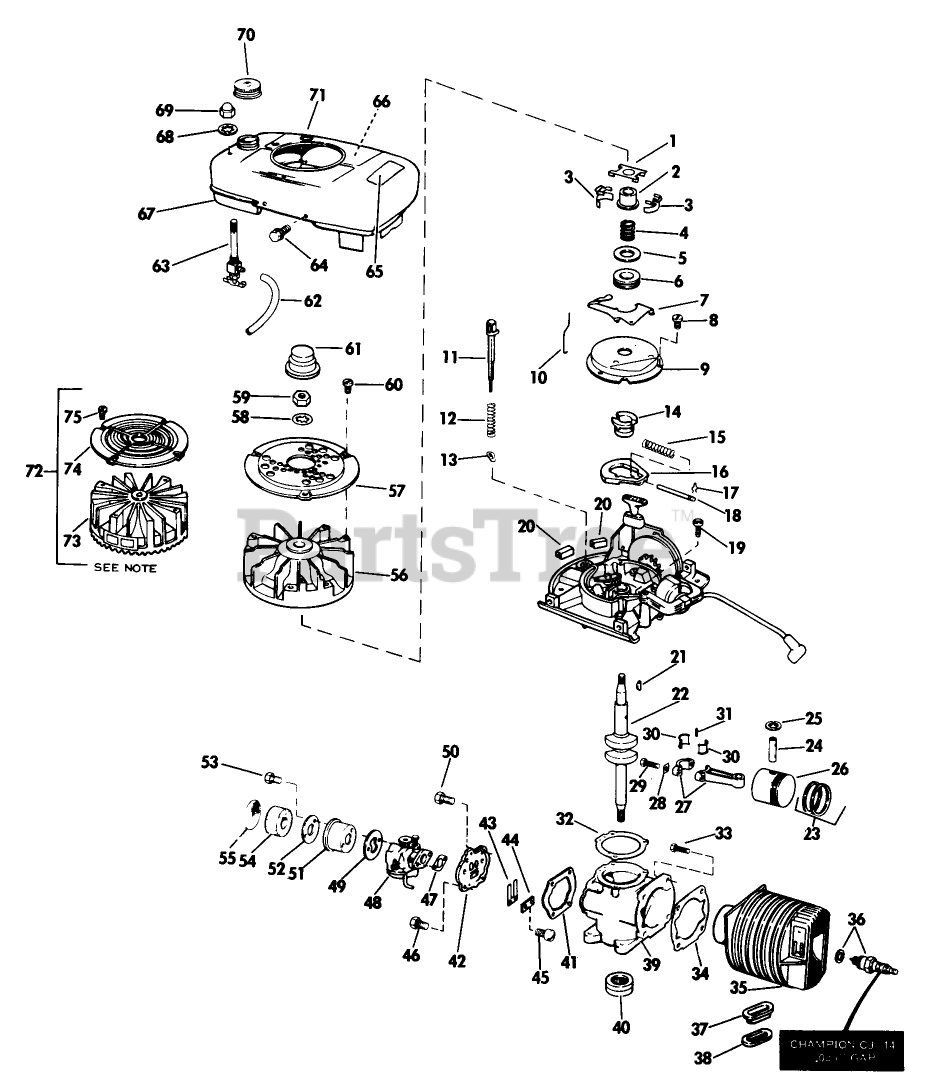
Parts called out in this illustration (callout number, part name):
2	COLLAR S
6	THRUST COLLAR S
7	LEVER-GOVERNOR S
8	SCREW S
9	DUST COVER S
12	SPRING S
14	SPARK ADV. S
15	SPARK ADV. SPRING S
16	FLYWEIGHT S
17	SPARK ADJ. SPRING
18	PIN,SPARK ADV. S
25	RING-RETAINING
30	LINER ASM
32	GASKET S
34	GASKET S
36	Spark Plug and Gasket
38	GASKET S
42	REED PLATE AY. S
44	PLATE-BACKUP, REED
46	SCREW S
47	GASKET S
49	GASKET S
50	SCREW S
52	BACK-UP PLATE
54	ELEMENT
60	SCREW F
63	VALVE&SCREEN SM
64	SCREW S
69	PALNUT S
72	Flywheel Screen Assy.
73	FLYWHEEL S
75	SCREW F
